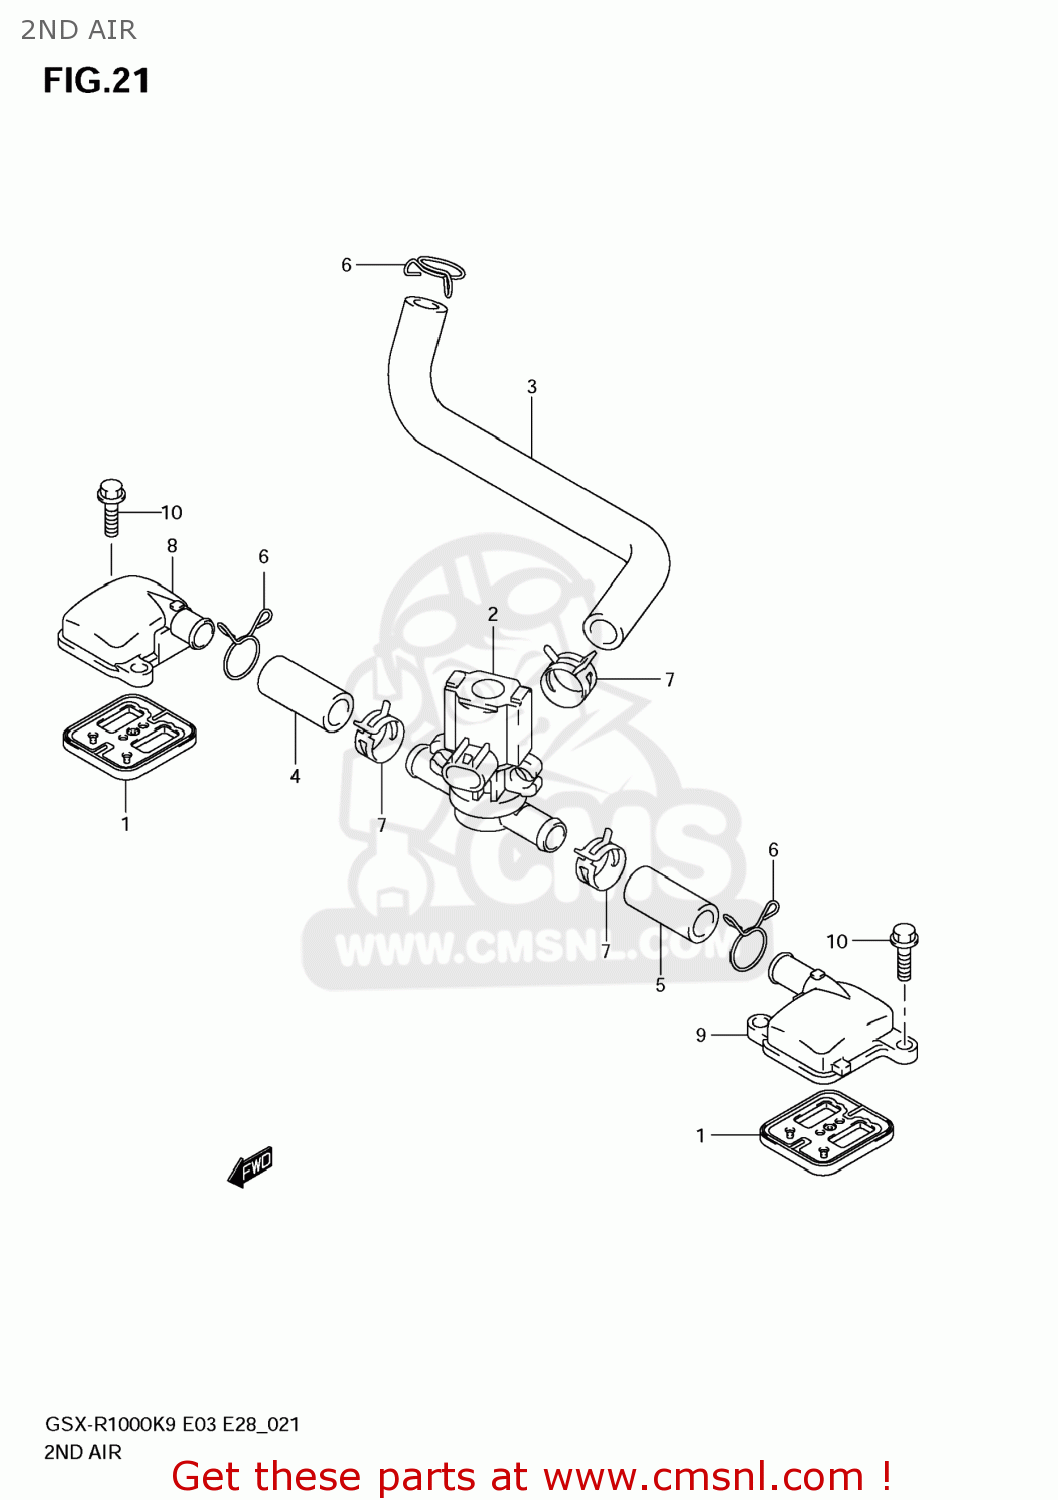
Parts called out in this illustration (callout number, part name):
1	VALVE ASSY,2ND AIR REED
2	VALVE ASSY,AIR CUT
3	HOSE,2ND AIR CLEANER
4	HOSE,2ND AIR VALVE,R
5	HOSE,2ND AIR VALVE,L
6	CLIP
7	CLIP
8	COVER,2ND AIR REED VALVE,R
9	COVER,2ND AIR REED VALVE,L
10	BOLT(6X20)
